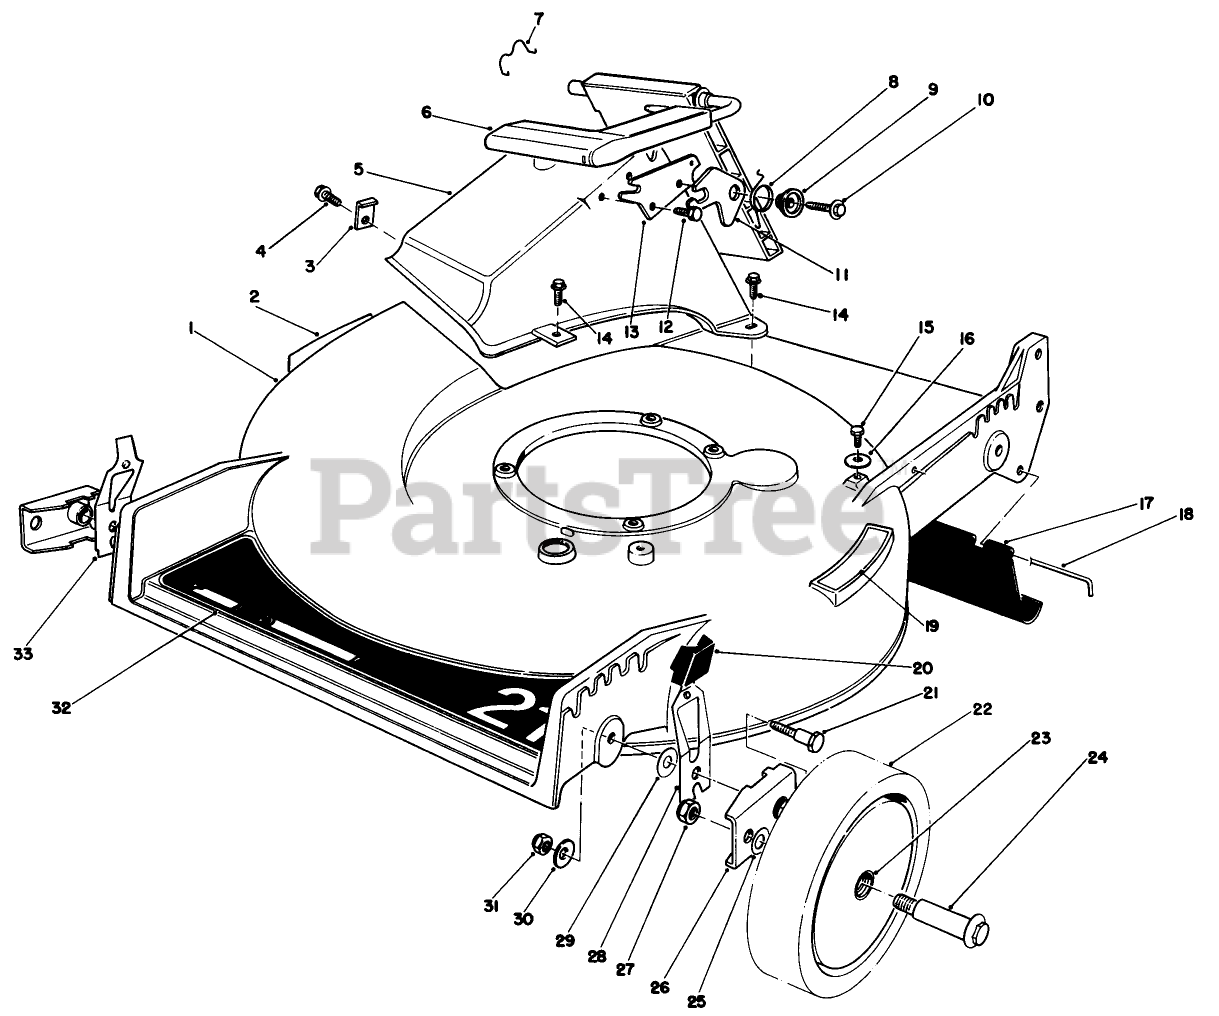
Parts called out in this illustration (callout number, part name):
2	DECAL-DANGER
3	TUNNEL CLIP
4	SCREW
7	DOOR RET SPRING
8	TORSION SPRING
9	DOOR SPACER
10	SCREW-HWH
11	SAFETY LATCH
12	SCREW-PLASTITE
13	DOOR LATCH PLATE
14	SCREW-HWH
15	SCREW-THD ROLL, HWH
18	ROD-SHIELD
19	STEP PAD DECAL
20	KNOB-ARM
21	PIVOT SCREW
23	BUSHING
24	BOLT-WHEEL
25	WASHER
26	HP PIVOT ARM ASM
29	WASHER-PIVOT
30	WASHER-BELLEVILLE
31	NUT-LOCK, NI
